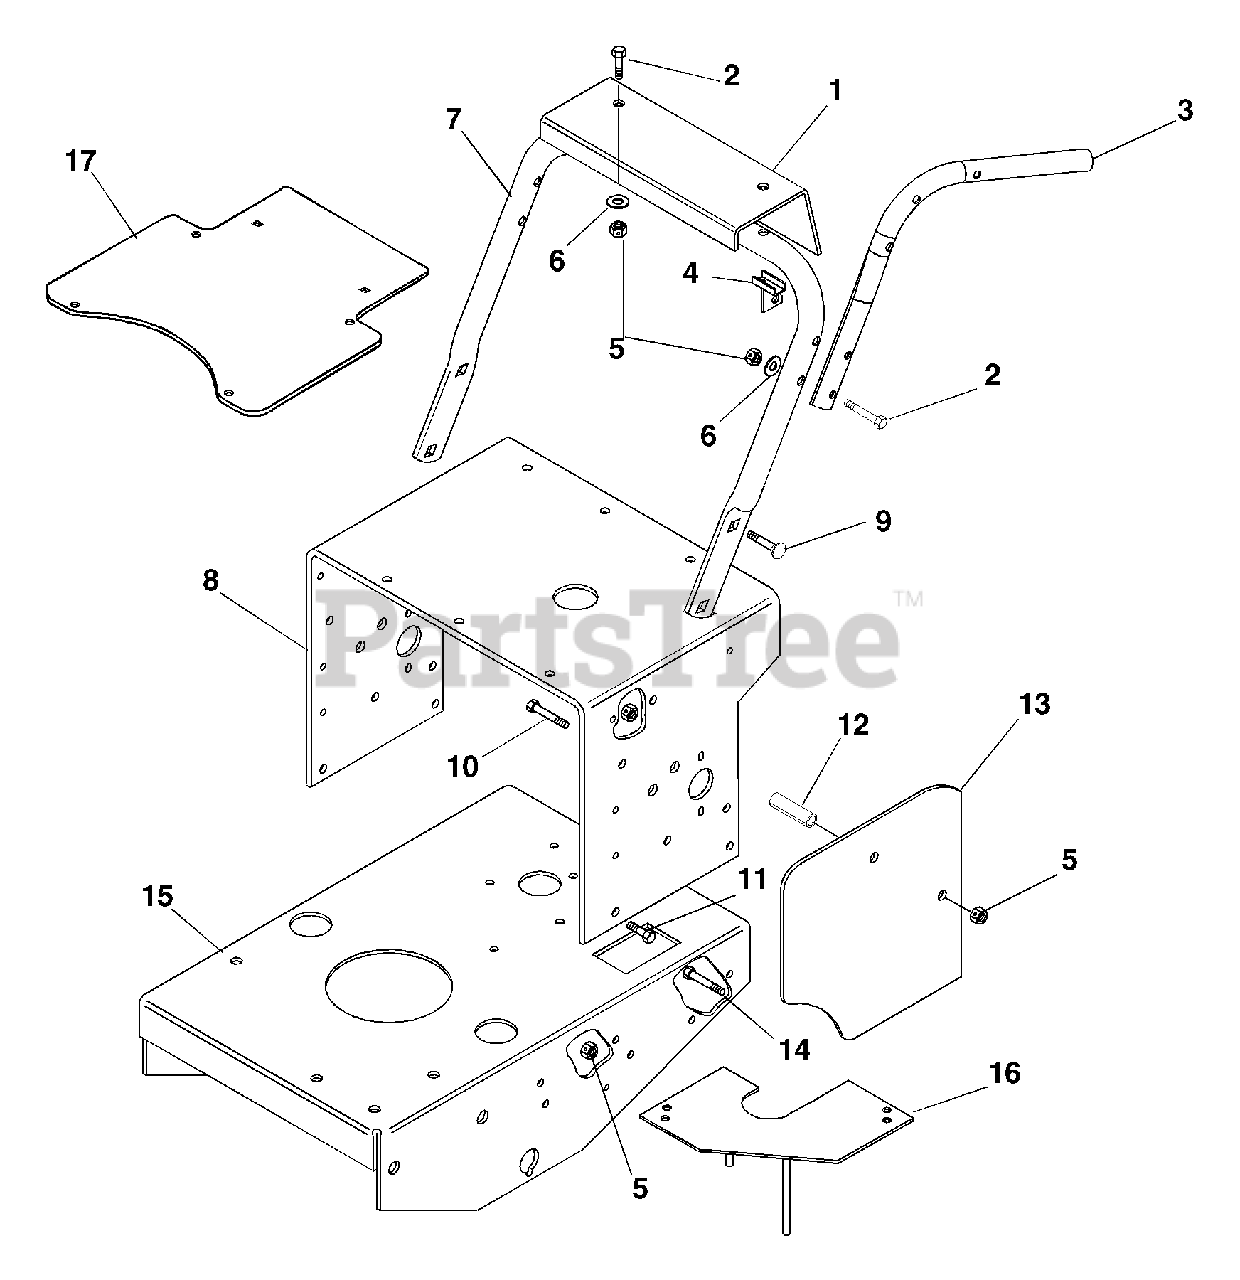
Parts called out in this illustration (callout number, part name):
1	PANEL, INSTRUMENT
2	@BLT-HEX .38-16X2.00 GR5 YWZC
3	HANDLE, LH
4	PTO LEVER MTG BKT
5	@NUT-LK-CTR .38-16 YWZC
6	@WSHR-FL-STL.406X.812X.065 YWZ
7	LOWER HANDLEBAR, PRO 150
8	FRAME, TOP - PRO 150
9	@BLT-RDHDSQNK .38-16X1.00 G2YZ
10	@BLT-HEX .38-16X4.00 GR5 YWZC
11	@BLT-HEX .38-16X1.00 GR5 YWZC
12	BSHG, SPACER, 3.25X3/8IDX5/8OD
13	GUARD, DRIVE.PRO-150 SIDE CVR
14	@BLT-HEX .38-16X1.50 GR5 YWZC
15	FRAME, MAIN - PRO 150
16	WLDT, BELT FINGER, PRO-150
17	PLATE, MOUNT
